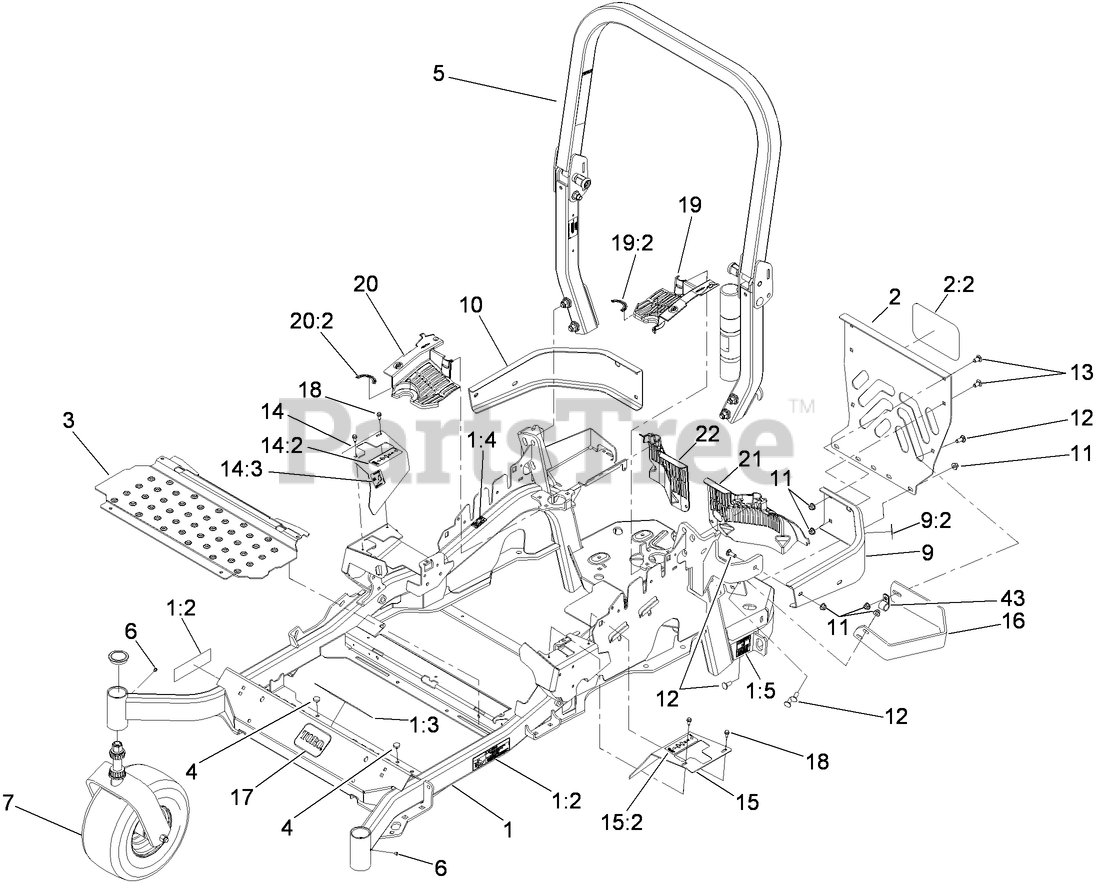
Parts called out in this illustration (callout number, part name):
1	MAIN FRAME ASM
1:2	DECAL-WARNING
1:3	DECAL-WARNING
1:4	DECAL-CAUTION
1:5	DECAL-BELT DRIVE
2	REAR GUARD ASM
2:2	DECAL
3	FLOORPAN
4	BUMPER
5	ROPS ASM
7	Caster Wheel ASM
9	LH BUMPER ASM
9:2	DECAL-CAUTION
10	BUMPER-RH
11	NUT-HF, NI
12	SCREW-CARR
13	SCREW-CARR
14	RH MOTION CONTROL COVER ASM
14:2	DECAL-MOTION CONTROL
14:3	DECAL-PARK BRAKE
15	LH MOTION CONTROL COVER ASM
15:2	DECAL-MOTION CONTROL
16	GUARD-MUFFLER
17	DECAL
18	SCREW-HWH
19	LH HYDRO GUARD ASM
19:2	DECAL-HYDRO OIL
20	RH HYDRO GUARD ASM
20:2	DECAL-HYDRO OIL
21	GUARD-HYDRO, REAR (LH)
22	GUARD-HYDRO, REAR (RH)
43	CLIP-LOOM
